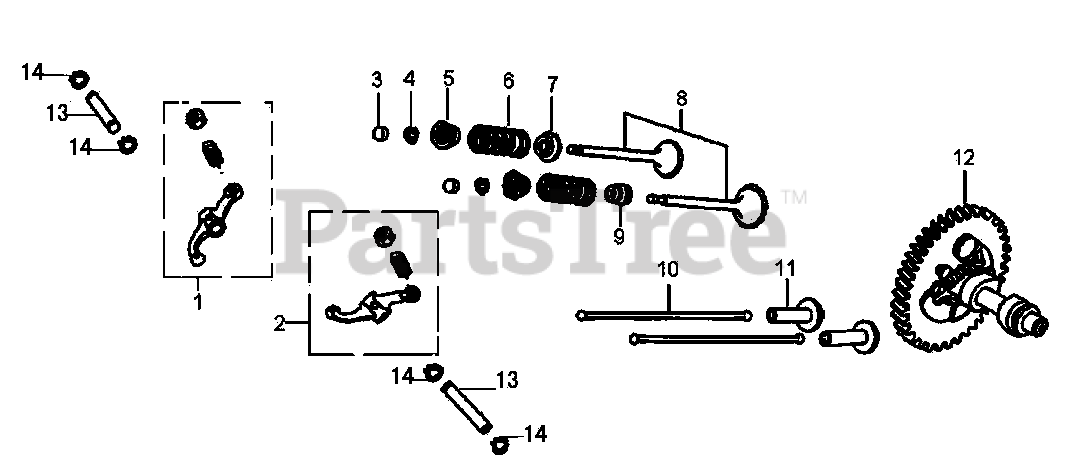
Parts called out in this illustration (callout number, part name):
1	ROCKER ARM ASSY.
2	ROCKER ARM ASSY.
3	ROTATOR,VALVE
4	VALVE LOCKER
5	RETAINER,VALVE SPRING
6	SPRING,VALVE
7	SEAT,VALVE SPRING
8	VALVE ASSY.
9	SEAL,VALVE STEM
11	LIFTER , VALVE
12	CAMSHAFT ASSY
13	ROCKER ARM SHAFT
